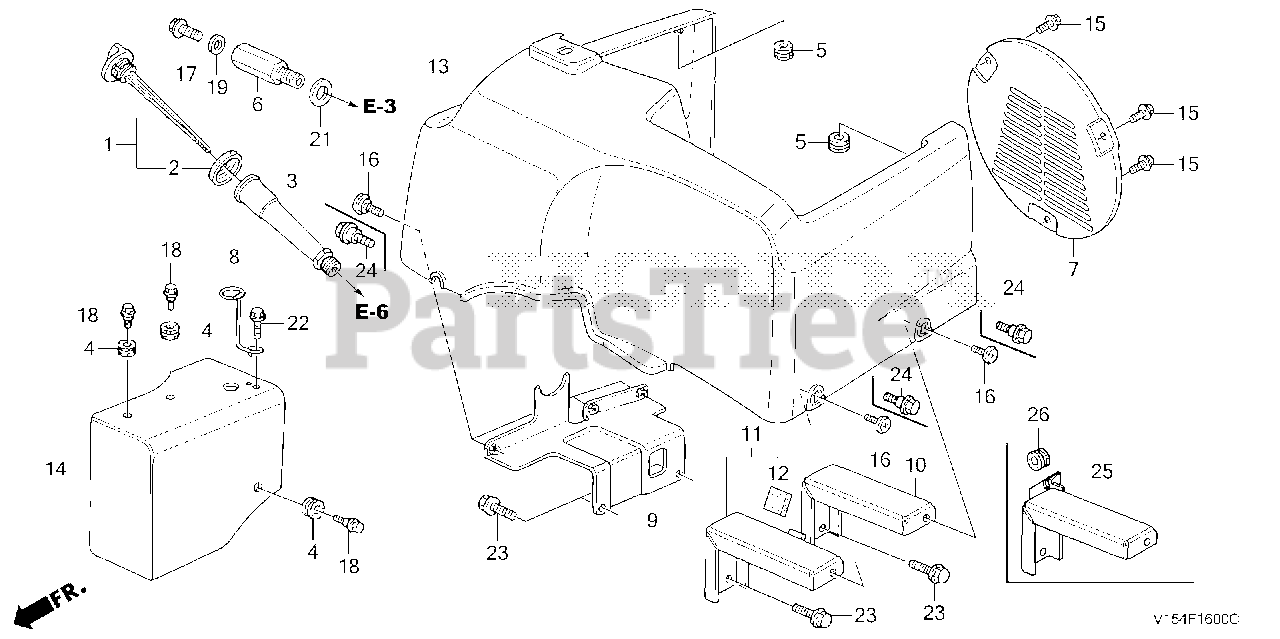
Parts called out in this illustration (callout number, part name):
1	CAP ASSY., OIL FILLER
2	GASKET, OIL FILLER CAP
3	EXTENSION, OIL FILLER
4	RUBBER, CANISTER MOUNTING
5	GROMMET, RESERVE TANK
6	EXTENSION, OIL DRAIN
8	GUIDE, CABLE
9	STAY, R. FR. COVER
11	STAY B, L. FR. COVER
12	RUBBER, STOPPER
13	COVER, FR. *R280* (POWER RED)
14	COVER, CHUTE MOTOR
17	BOLT, DRAIN PLUG
18	BOLT, RADIATOR SETTING
19	WASHER, DRAIN PLUG (10.2MM)
21	WASHER, DRAIN PLUG (12MM)
22	BOLT, FLANGE (6X16)
23	BOLT, FLANGE (8X16) Use from Engine SN 1000016.
24	BOLT, SPLASH GUARD
25	STAY A, L. FR. COVER
26	RUBBER, SCREEN SETTING
